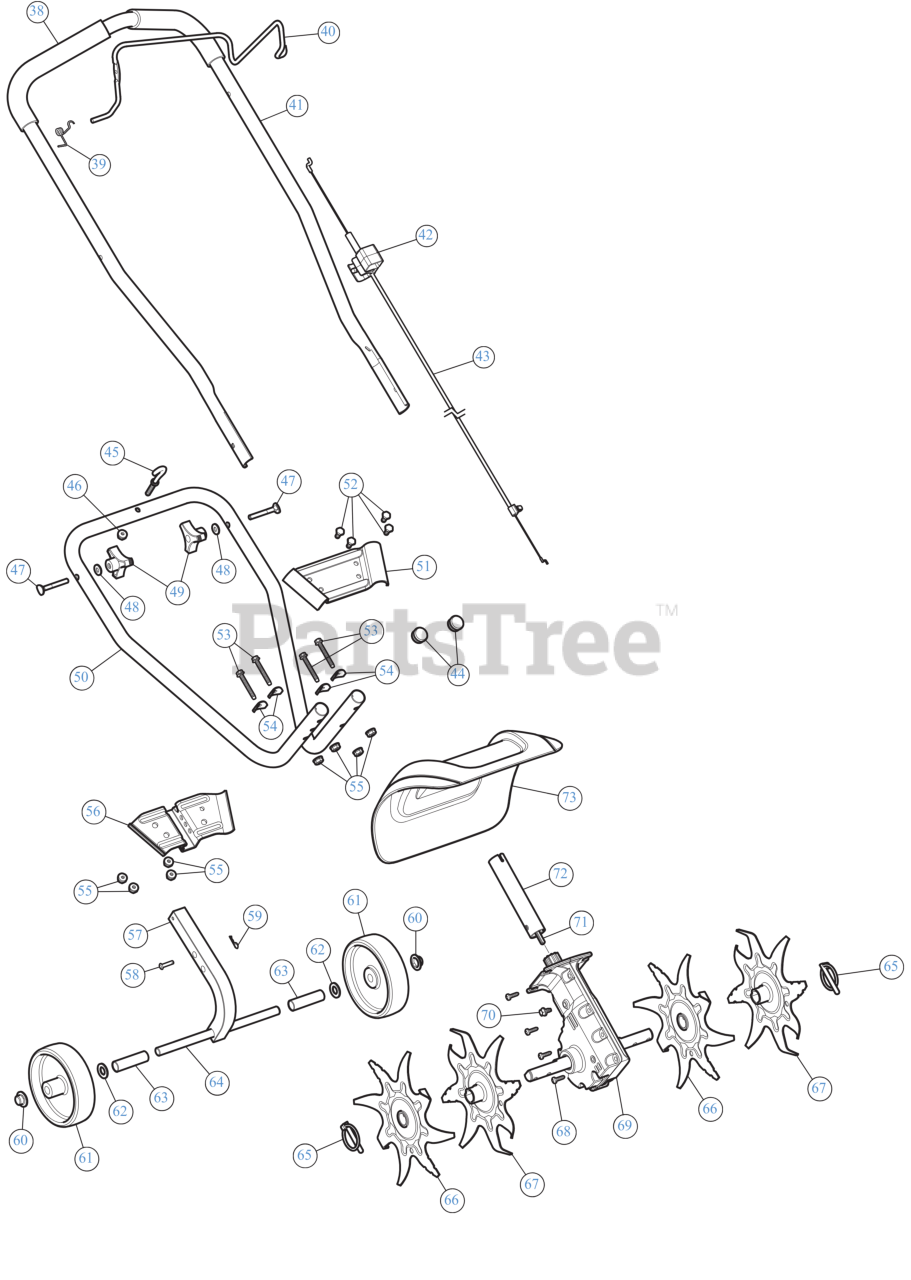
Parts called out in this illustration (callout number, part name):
38	FOAM GRIP - 9"
39	TORSION SPRING
40	BAIL CONTROL
41	HANDLE UPR
42	SW, MOMENTARY ON/O
43	THROTTLE CABLE
45	ROPE GUIDE
46	FLANGE LOCK NUT
47	BOLT, CARRIAGE CRV
48	SADDLE WASHER
49	KNOB, 3-PRONG ¼ "-
50	HANDLE LOWER
51	BRACKET UPR
52	SCREW 1/4-20X.5 GR5
53	SCREW 1/4-20 x 1.750
54	SADDLE WASHER
55	LOCK NUT 1/4
56	BRACKET LOWER
57	TUBE SQUARE
58	CLEVIS PIN
59	COTTER PIN .072 DIA
60	PUSH CAP
61	WHEEL:5.0 x 1.38
63	SPACER
65	CLICK PIN
66	TINE ASSEMBLY (LH)I (RH)O
67	TINE ASSEMBLY (LH)O (RH)I
68	SCREW #
69	GEARBOX ASSEMBLY CULT
70	SCREW 1/4-20 X.500
71	SHAFT-FLEX
72	BOOM ASSEMBLY
73	TINE SHIELD
